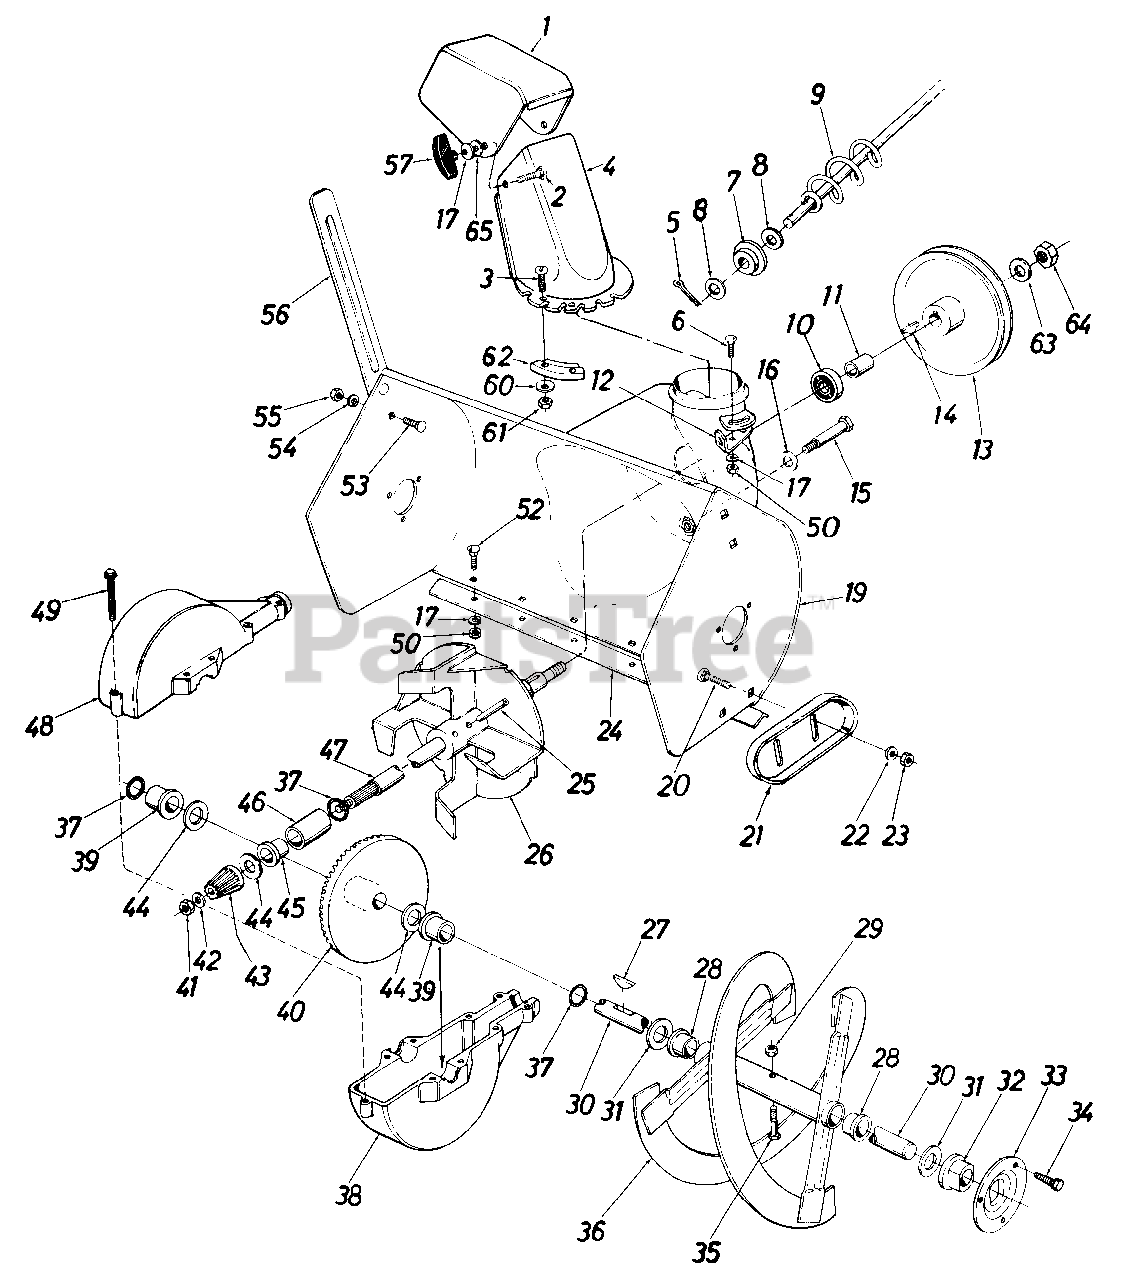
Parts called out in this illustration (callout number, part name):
1	Top Chute (Black)
2	Carriage Bolt 5/16-18 x 1.0"
3	Truss Mach. Scr. Bolt 1/4-20 x .75"
4	Chute (Black)
5	Cotter Pin
6	Carriage Bolt 5/16-18 x .75"
7	Bushing
8	Fl-Wash. .385 I.D. x .62" O.D.
9	Chute Crank Ass'y.
10	Ball Brg. .62" I.D. x 1.38" O.D.
11	Spacer .63" I.D. x .88" O.D. x .900" Lg.
12	Chute Crank Brkt.
13	1/2" "V" Pulley .625" I.D. x 7.50" O.D.
14	#61 Hi-Pro Key 3/16" x 5/8" Dia.
15	Shld. Bolt .50" Dia. x 2.11"
16	Bell-Wash. .40" I.D. x .88" O.D. x .06
17	Bell-Wash. .34" I.D. x .88" O.D.
20	Carriage Bolt 3/8-16 x .62"
21	Slide Shoe
22	Bell-Wash. 3/8" I.D.
23	Hex Jam Nut 3/8-16 Thd.
24	20" Shave Plate
24	24" Shave Plate
25	Spring Pin Spiral 1/4" Dia. x 1.50" Lg.
26	11" Dia. Blower Fan Ass'y.
27	#9 Hi-Pro Key 3/16 x 3/4" Dia.
28	Flange Brg. .75" I.D. x .88" O.D. x .62
29	Hex Ins. L-Nut 5/16-18
30	Spiral Axle
31	Fl-Wash. .75" I.D. x 1.50" O.D. x .06
32	Flange Brg. w/Flats .755" I.D.
33	Bearing Housing
34	Hex Wash. Hd. Self-Tap Scr. 5/16-24 x .50" Lg.
35	Hex Bolt 5/16-18 x 1.50" Lg.
36	20" Spiral Ass'y. - L.H.
36	20" Spiral Ass'y. - R.H.
36	24" Spiral Ass'y. - L.H.
36	24" Spiral Ass'y. - R.H.
37	O-Ring - 3/4" I.D.
38	Bevel Gear Housing - Lower Half
39	Plastic Flange Brg. .755" I.D.
40	Bevel Gear
41	Hex Cent. L-Nut 5/16-24 Thd.
42	Fl-Wash. .34" I.D. x .62" O.D. x .06
43	Pinion Gear
44	Fl-Wash. .75" I.D. x 1.25" O.D. x .06
45	Flange Brg. .755" I.D.
46	Sleeve Brg. .755" I.D.
47	Blower Axle
48	Bevel Gear Housing - Upper Half
49	Hex Wash. Hd. Self-Tap Scr. 1/4-20 x 1.00" Lg.
50	Hex Nut 5/16-18 Thd.
52	Carriage Bolt 5/16-18 x .62" Lg.
53	Carriage Bolt 5/16-18 x .62" Lg.
54	L-Wash. 5/16" I.D.
55	Hex Nut 5/16-18 Thd.
56	Drift Cutter Bar
60	Fl-Wash. 1/4" I.D.
61	Hex L-Nut 1/4-20 Thd.
62	Chute Flange Keeper
63	Fl-Wash. .64" I.D. x .94" O.D. x .06
64	Hex Jam Nut 5/8-18 Thd.
65	Fl-Wash. .344 I.D. x 1.125 O.D.
